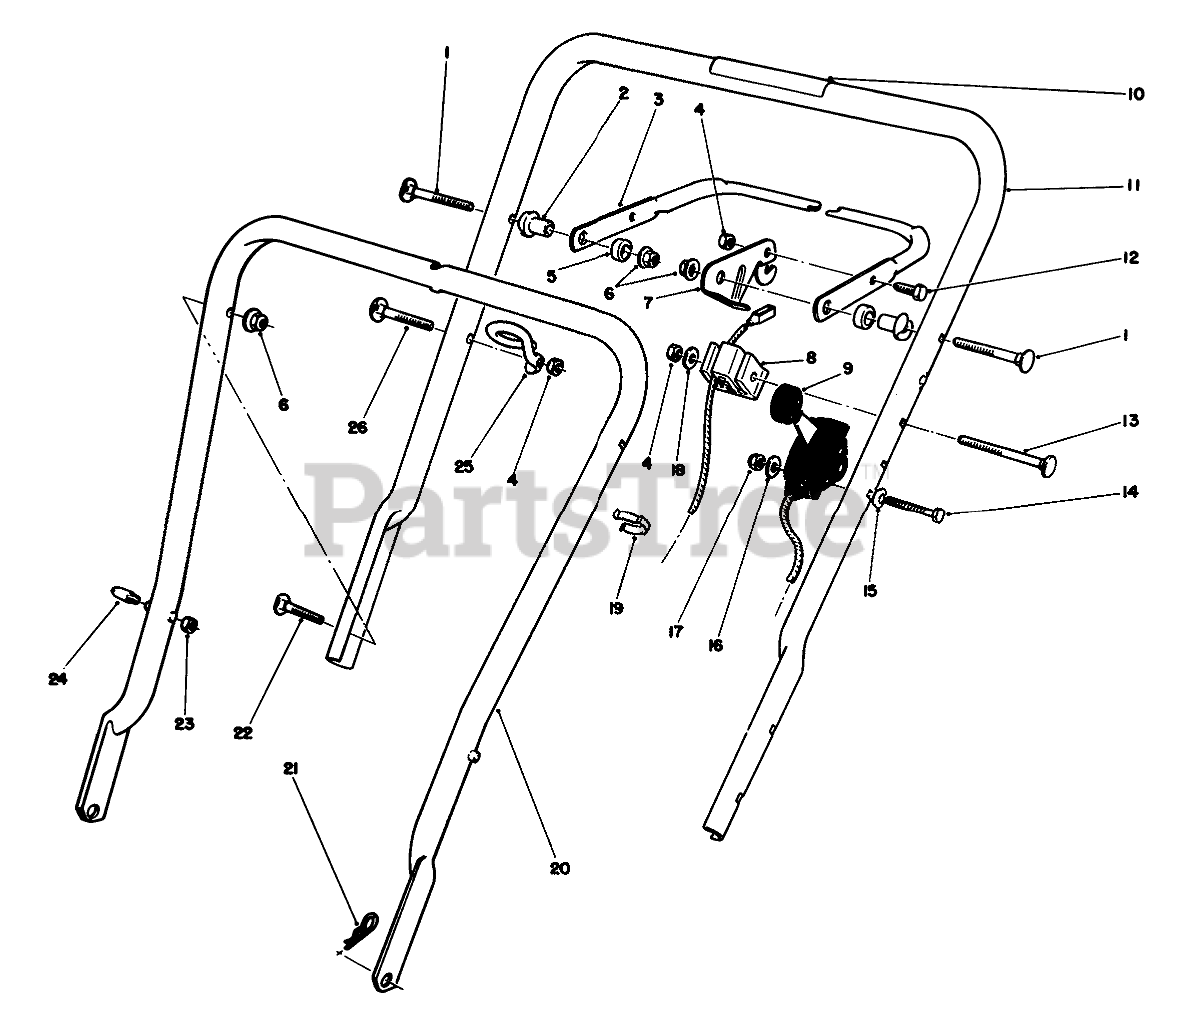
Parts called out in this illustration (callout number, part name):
1	5/16-18 X 2 HNDLE SCREW
2	SPACER-SUPPORT
3	CONTROL BAR PROMO
3	Bar-Control
4	NUT-LOCK, NI
5	SPACER-NYLON
6	NUT-LOCK, NI
7	Lever-Control
8	SUPPORT-CABLE
9	Control-Throttle (Bend Type #1)(Sheath Lg. 35-1/4-)(Wire Log. 2-3/8")
9	THROTTLE CONT-SERVICE
10	WARNING DECAL
11	Handle-Upper (Incl. Ref. #10)
12	SCREW-HH
13	HANDLE SCREW
14	SCREW-SHH
15	Washer-Curved
16	WASHER-FLAT
17	NUT-LOCK, NI
18	WASHER-FLAT
19	BOWDEN CLIP
20	LOWER HANDLE ASM
21	PIN-COTTER, HAIR
22	SCREW
23	NUT-LOCK, NI
24	HANDLE PIN
25	Guide
26	HANDLE SCREW
